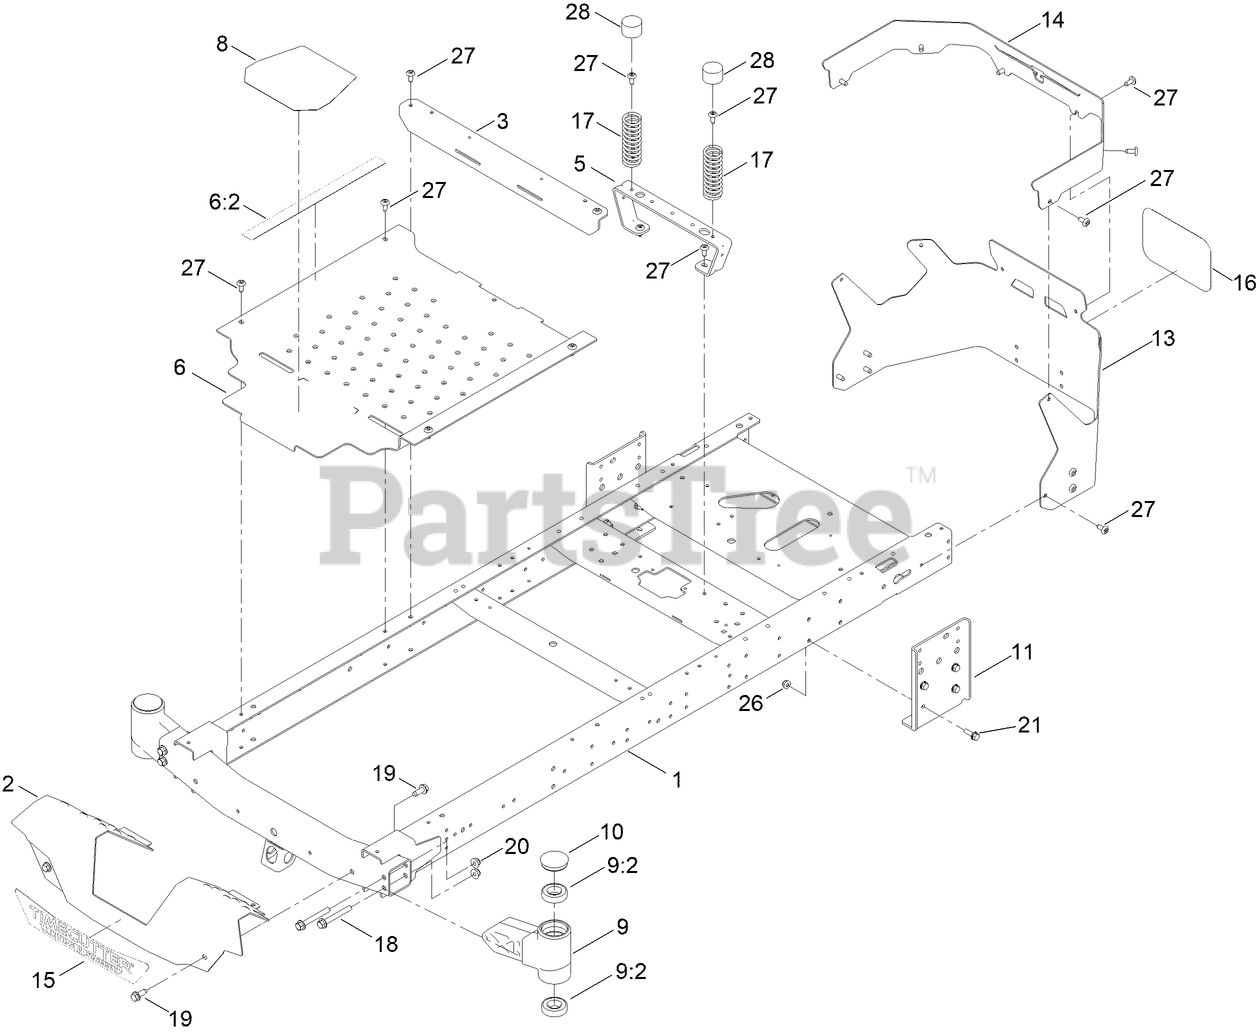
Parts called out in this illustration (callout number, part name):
1	FRAME ASM [RED]
2	FOOTREST
3	BRACE-CROSS
5	SUPPORT-SEAT
6	PAN-FLOOR ASM
6:2	DECAL - WARNING
8	TREAD-STEP
9	AXLE STUB ASM
9:2	BEARING-BALL
10	CAP-GREASE
11	PLATE-MOUNT, DRIVE
13	GUARD-REAR
14	GUARD-REAR, UPPER
15	DECAL-TIMECUTTER
16	DECAL-LOGO, SILVER
17	SPRING-COMPRESSION
18	SCREW-HHF
19	SCREW-HWH
20	NUT-HF, NI
21	SCREW-HHF
26	NUT-HF
28	CAP-PROTECTOR
